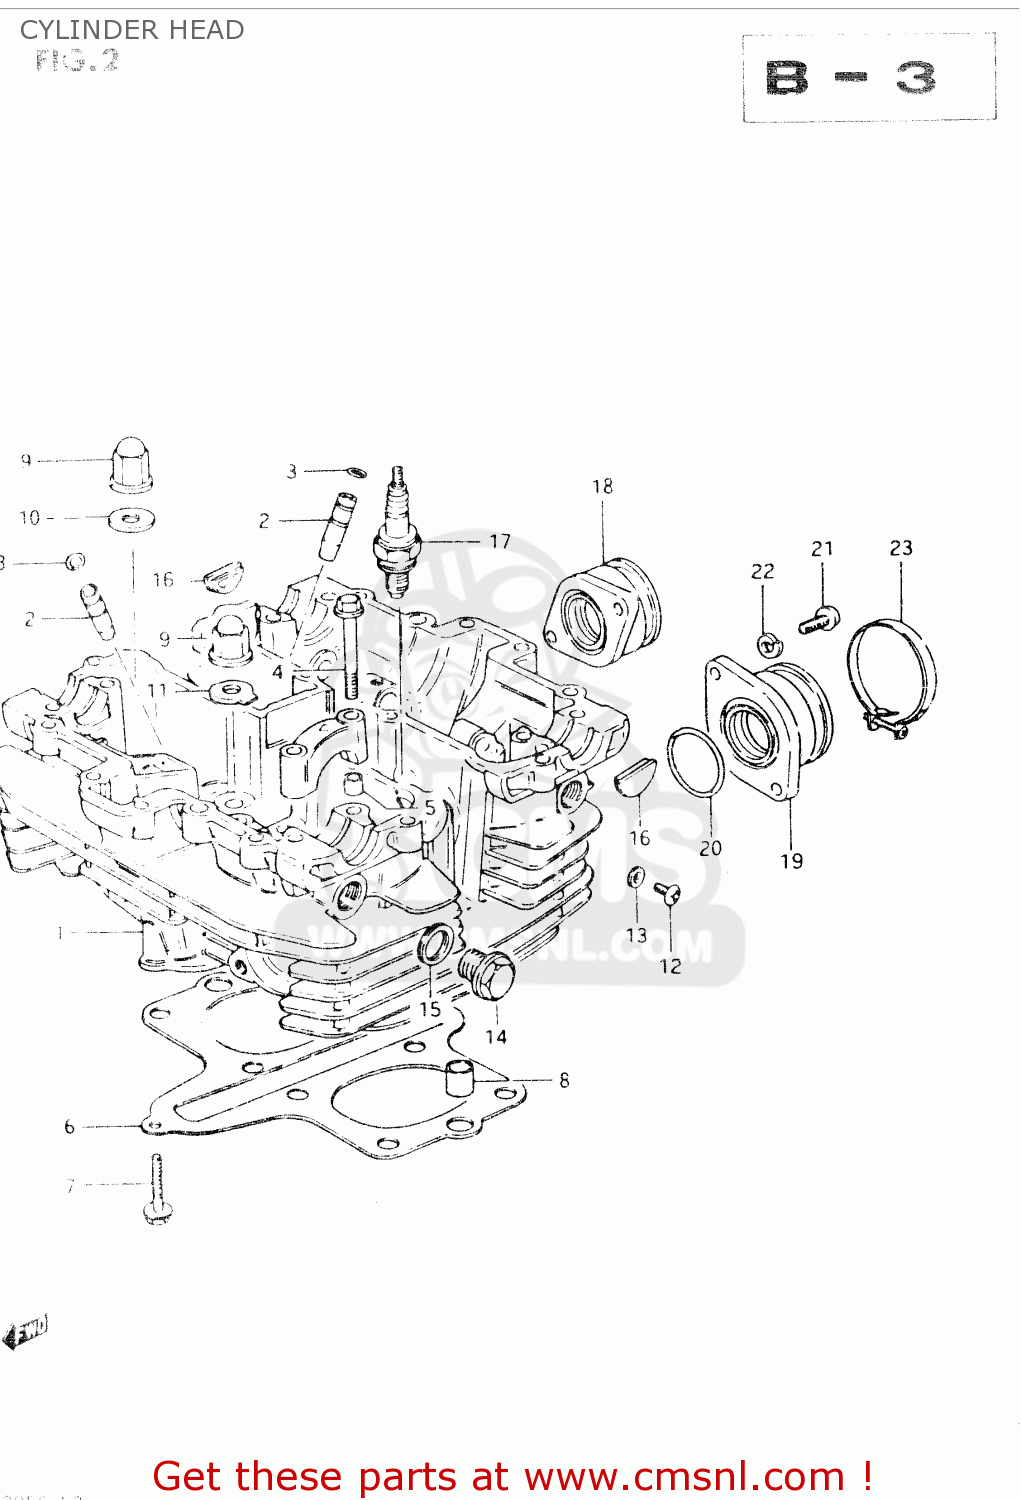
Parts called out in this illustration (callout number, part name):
1	HEAD ASSY, CYLINDER
2	GUIDE,INTAKE VALVE
3	RING,SNAP
4	BOLT(6X39)
5	PIN(6.2X8X11)
6	GASKET (MCA)
7	BOLT 6X30
8	PIN
9	NUT
10	GASKET(10.5X22X2) (NAS)
11	GASKET(10X22X2.3) (NAS)
12	SCREW
13	GASKET(5.3X9.3X1.2) (NAS)
14	PLUG (14X12)
15	GASKET(14X19.2X2) (NAS)
16	PLUG
17	SPARK PLUG D8EA
18	PIPE,INTAKE,R
19	PIPE,INTAKE,L
20	O RING(D:2.4,ID:33.7)
21	SCREW
22	WASHER,LOCK
23	CLAMP
